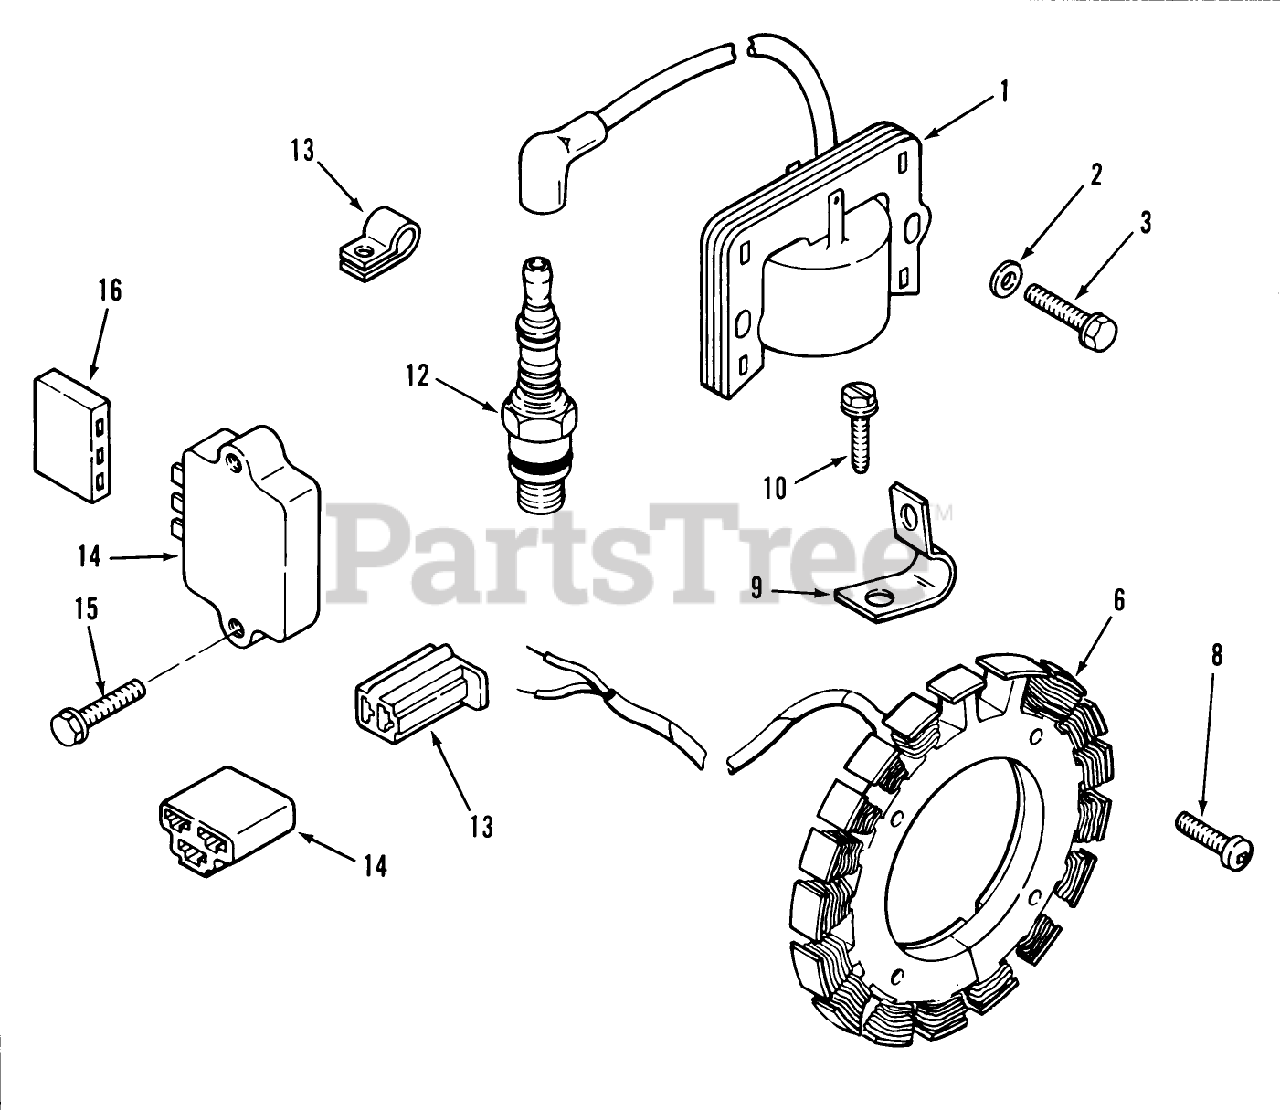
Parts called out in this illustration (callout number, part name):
1	KOHLER 47-584-02
2	KOHLER X-25-79
3	KOHLER X-156-1
6	KOHLER 237878
8	KOHLER X-67-51
9	KOHLER X-728-1
10	KOHLER X-67-59
12	KOHLER 235041-5
13	KOHLER 210281
14	KOHLER 41-403-05
15	KOHLER X-132-4
16	KOHLER 236602
